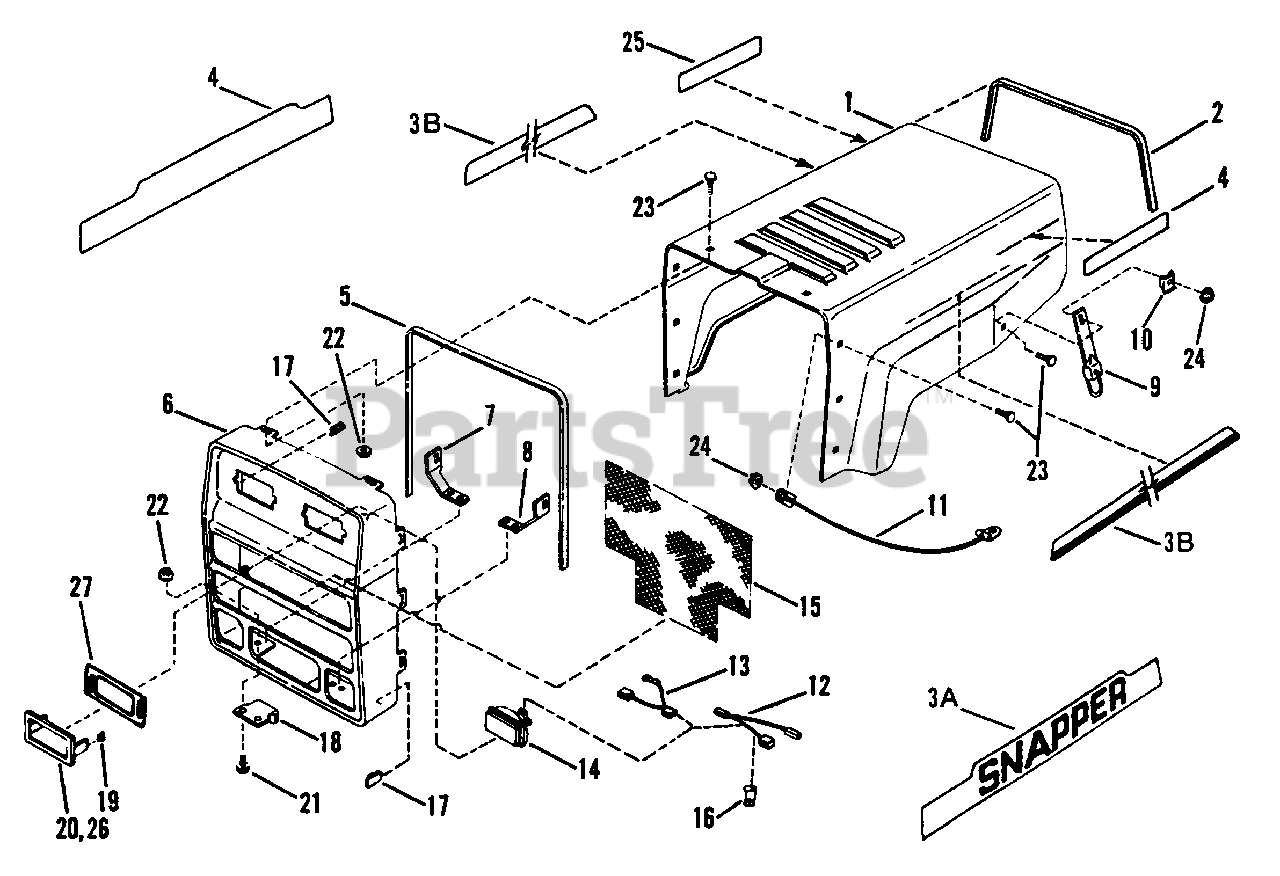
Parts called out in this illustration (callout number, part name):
1	HOOD, YT Series Tractor
2	TRIM, Hood
3A	DECAL, Snapper L.H.
3B	DECAL, Stripe
4	DECAL, Snapper R.H.
5	GASKET, Grill
6	GRILL
7	BRACE, Grill, R.H.
8	BRACE, Grill, L.H.
9	LATCH, Hood Retaining
10	CLIP, Hood Retainer
11	CABLE, Hood Stop
12	HARNESS, Head Lamp Wiring
13	HARNESS, Head Lamp Ground Wiring
14	HEAD LAMP
15	MESH, Grille
16	CLIP, Wiring Harness
17	CLIP
18	HINGE, Hood
19	CLIP, Head Lamp Mounting (Use 7017591 Wire Retainer & 7033211)
20	BEZEL, Head Lamp Mount (Use 7033211 & 7017591)
21	BOLT, 1/4-20 x 5/8" Hex Flange Lock, Grade 5
22	NUT, 1/4-20 Hex Flange Lock
23	BOLT, 1/4-20 x 5/8" Flat Head Carriage
24	NUT, 1/4-20 Hex Fl. Top Lock
25	DECAL, Snapper
26	BEZEL (Has a slot or hole in retainer tang)
27	REINFORCEMENT, Bezel
